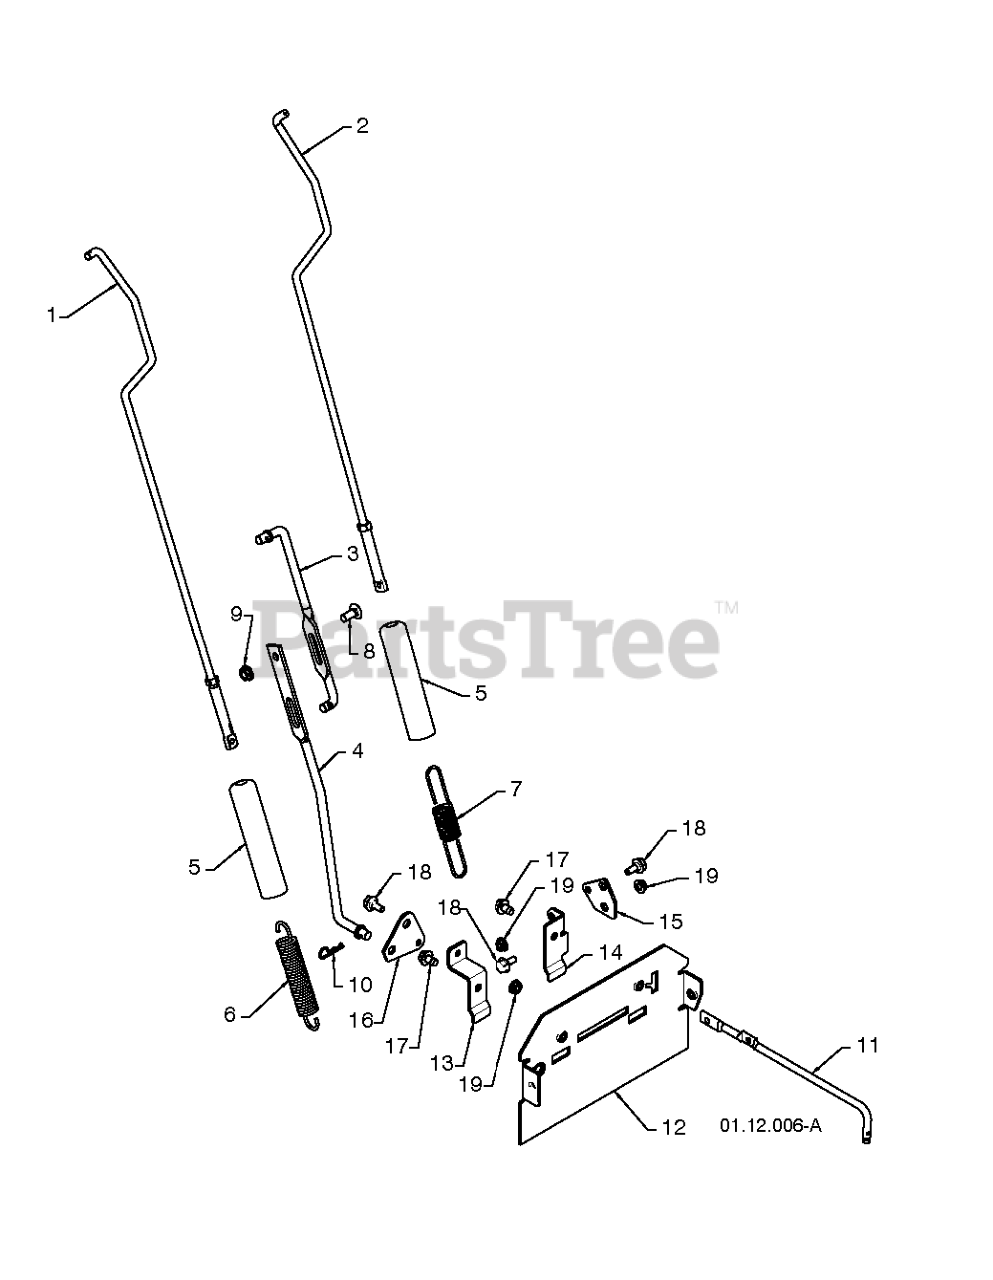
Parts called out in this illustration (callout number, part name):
1	ROD.ASM.IMPELLER
2	ROD.ASM.TRACTION
3	ROD, UPPER SPEED CONTROL
4	ROD, LOWER SPEED CONTROL.SNOW
5	SLEEVE, SPRING
6	SPRING, AUGER CONTROL
7	SPRING, TRACTION DRIVE
8	BOLT
9	NUT.FLANGE.5/16
10	SPRING RETAINER
11	ROD.CLUTCH.YELLOW.ZINC(VT)
12	PLATE.REAR.SNOW.PNT.ORANGE
13	BRACKET.SHIFTER.PLATE.BZP
14	BRACKET.CLUTCH.PLATE.BZP
15	PLATE.CLUTCH.BZP
16	PLATE.SHIFTER.BZP
17	Screw 5/16-18 x 1/2 Hex, Self Tapping 5/16-18 x 1/2
18	BOLT.SHOULDER.3/X.25
19	NUT.HEX.FLANGE.1/4
